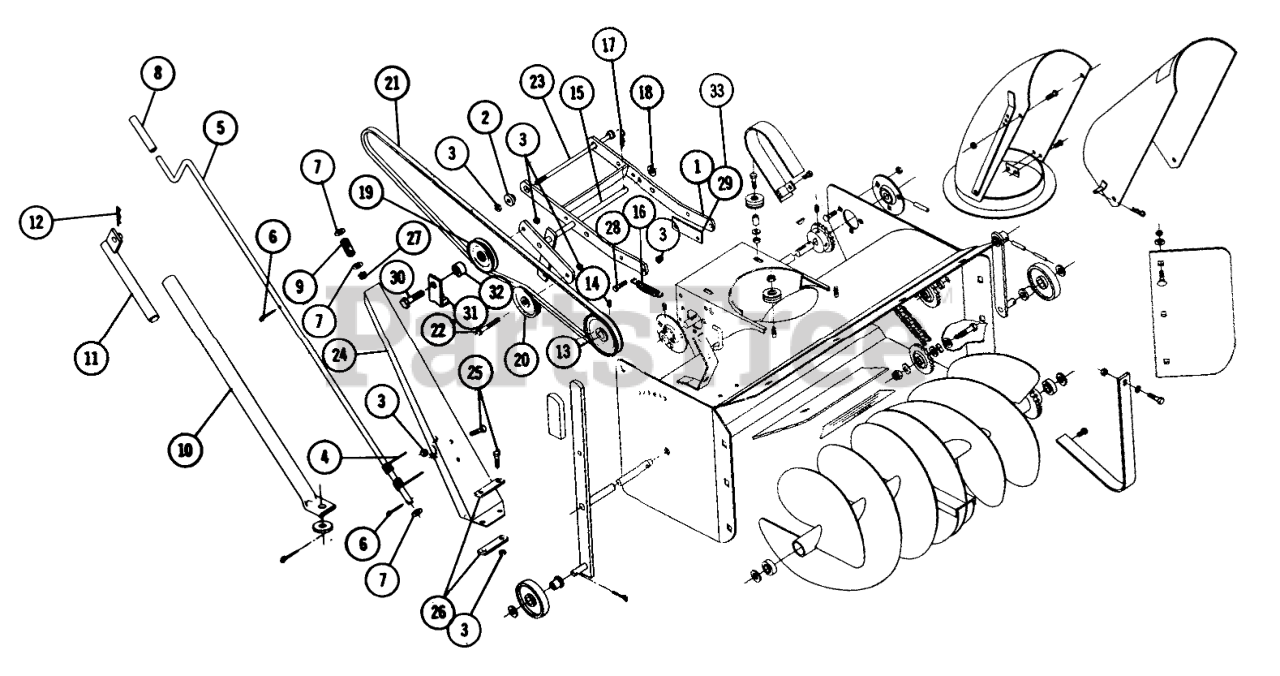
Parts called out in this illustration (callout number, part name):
6	Cotter Pin
7	Washer
8	Tube
9	SPRING-COMPRESSION
11	Lift Rod
12	Hairpin
14	Set Screw
15	Idler Arm Ass-y
16	SPRING *R
17	Hairpin
18	Washer
21	V-BELT
22	Bolt, 3/8-16 x 1/2
25	Bolt 3/8-16 x 3/4
27	NYLINER BUSHING
28	Bolt 3/8-16 x 1
29	Shim
30	Bolt Hex 3/8-16
